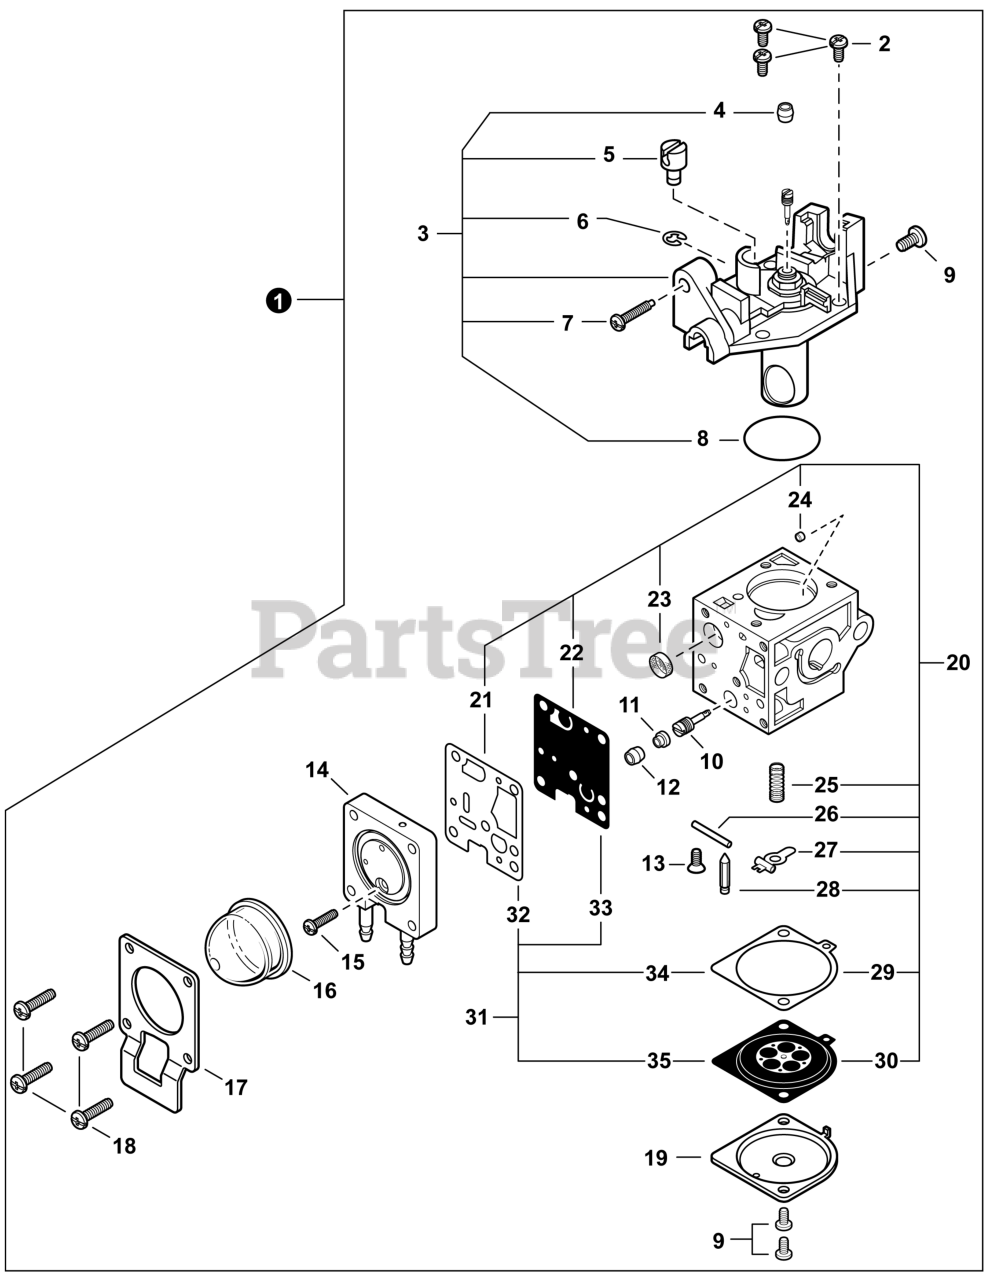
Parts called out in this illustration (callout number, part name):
1	CARBURETOR - Z011-0GB
3	COVER KIT, ROTOR
7	SCREW, IDLE ADJUST
10	NEEDLE, HIGH SPEED
11	CAP, LIMITER
14	BODY ASSY, PURGE
16	BULB, PURGE
17	RETAINER, PURGE BULB
19	COVER, METERING DIAPHRAGM
20	REPAIR KIT, CARBURETOR
21	GASKET, PUMP
22	DIAPHRAGM, PUMP
23	SCREEN, FUEL INLET
24	GUIDE, ROLLER
25	SPRING, METERING LEVER
26	PIN, METERING LEVER
27	LEVER, METERING
28	VALVE, INLET NEEDLE
29	GASKET, METERING DIAPHRAGM
30	DIAPHRAGM, METERING
31	GASKET / DIAPHRAGM KIT
32	GASKET, PUMP
33	DIAPHRAGM, PUMP
34	GASKET, METERING DIAPHRAGM
35	DIAPHRAGM, METERING
